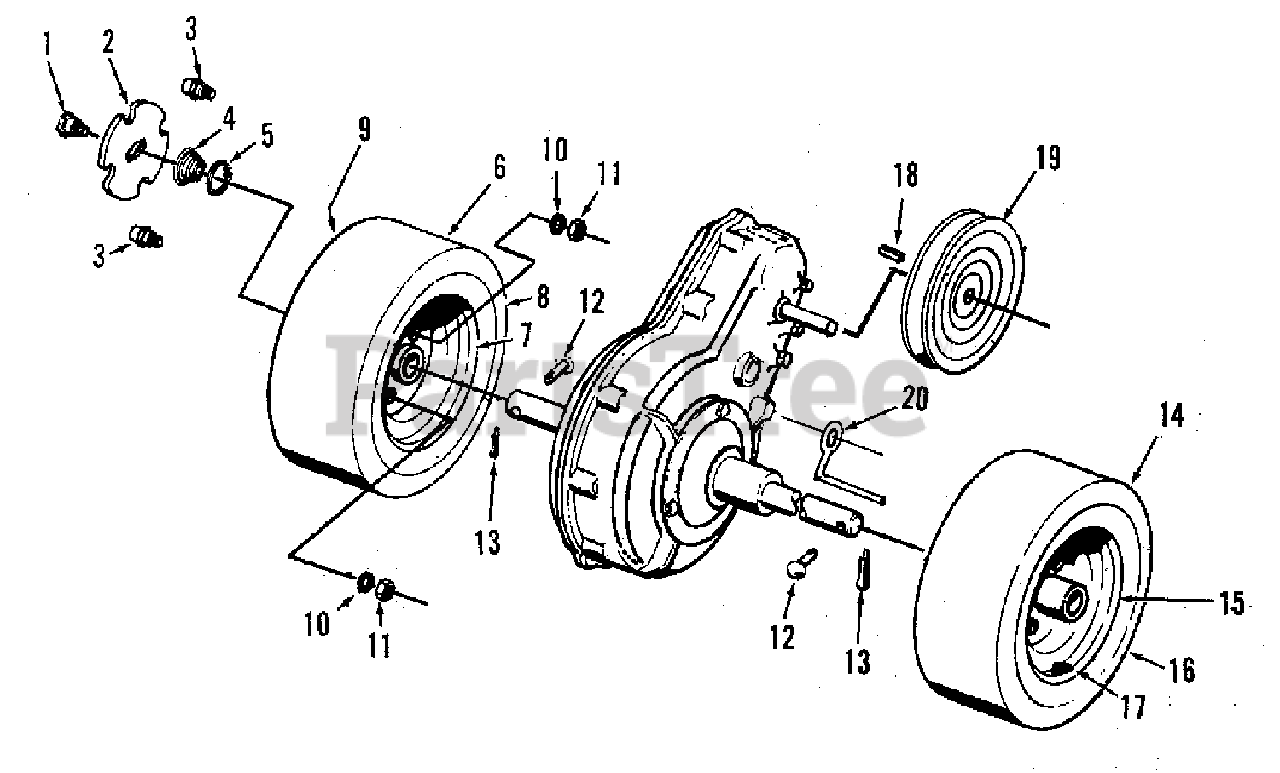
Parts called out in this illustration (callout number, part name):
1	BOLT, Shoulder
5	RING, Retaining
6	WHEEL & TIRE ASSEMBLY, L.H.
8	TIRE, 5.30/4.50 X 8
9	STEM & CAP, Valve
10	WASHER, Flat
11	NUT, Full Hex Lock, 3/8-16
13	PIN, Cotter, Extension Prong
14	WHEEL & TIRE ASSEMBLY, R.H.
16	TIRE, 5.30/4.50 X 6
17	STEM & CAP, Valve
